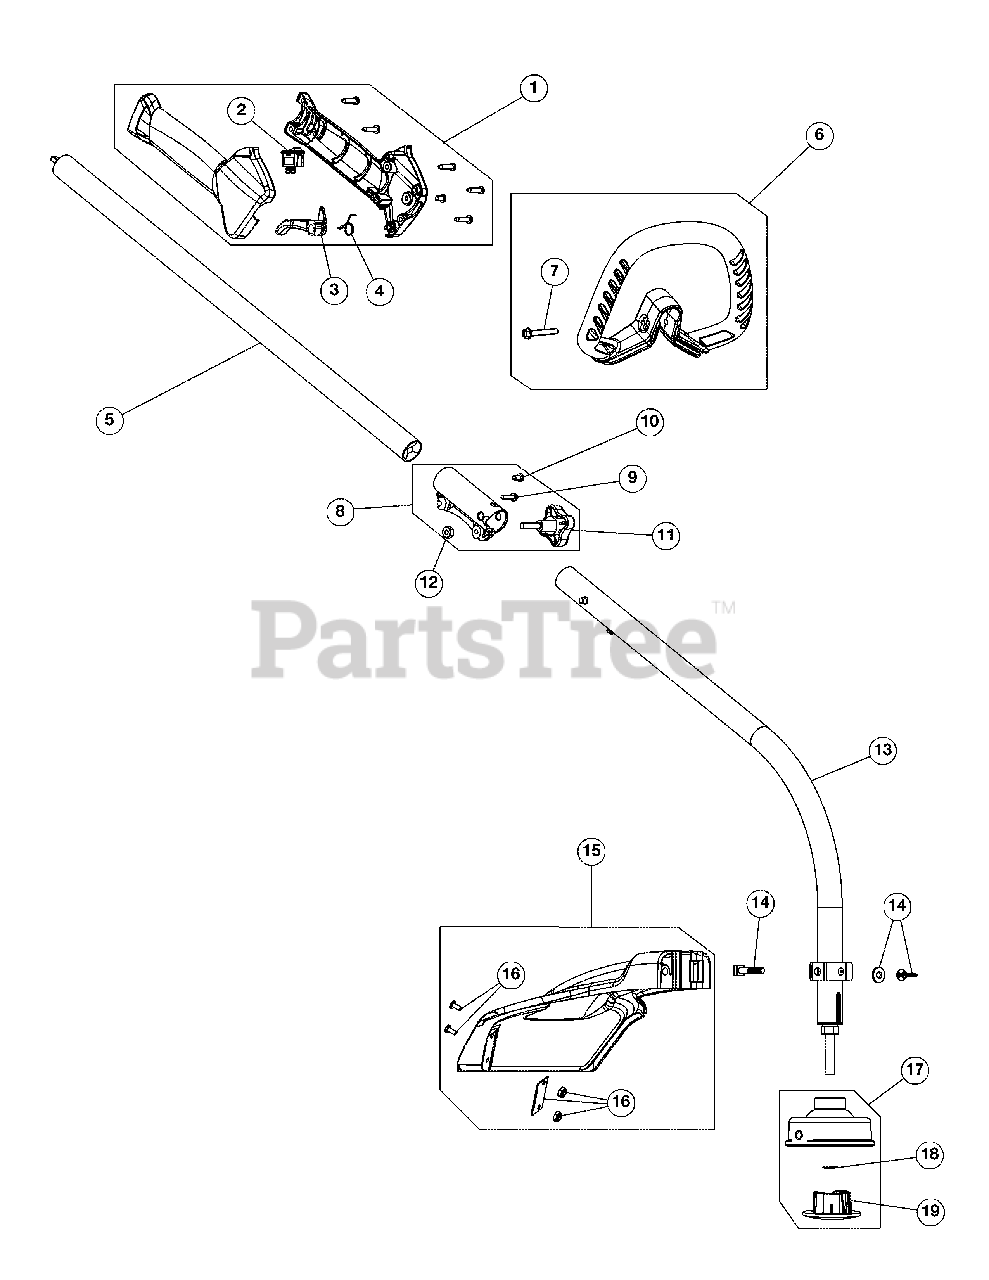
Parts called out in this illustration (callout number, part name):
1	Throttle Housing Assembly (Incl. 2-4)
3	Throttle Trigger
4	Throttle Trigger Spring
5	Upper Shaft Housing Assembly
6	D-Handle (Incl. 7)
7	D-Handle Hardware Assembly
8	Split Boom Coupler (Incl. 9-12)
9	Anti-Rotation Screw
11	Adjustment Knob
12	Knob Retainer Nut
13	Lower Shaft Housing Assembly
14	Shield Mounting Hardware
15	Shield Assembly (Incl. 16)
16	Blade Assembly
17	Fixed String Head Assembly (Incl. 18 & 19)
18	Retainer
19	Fixed String Cap
